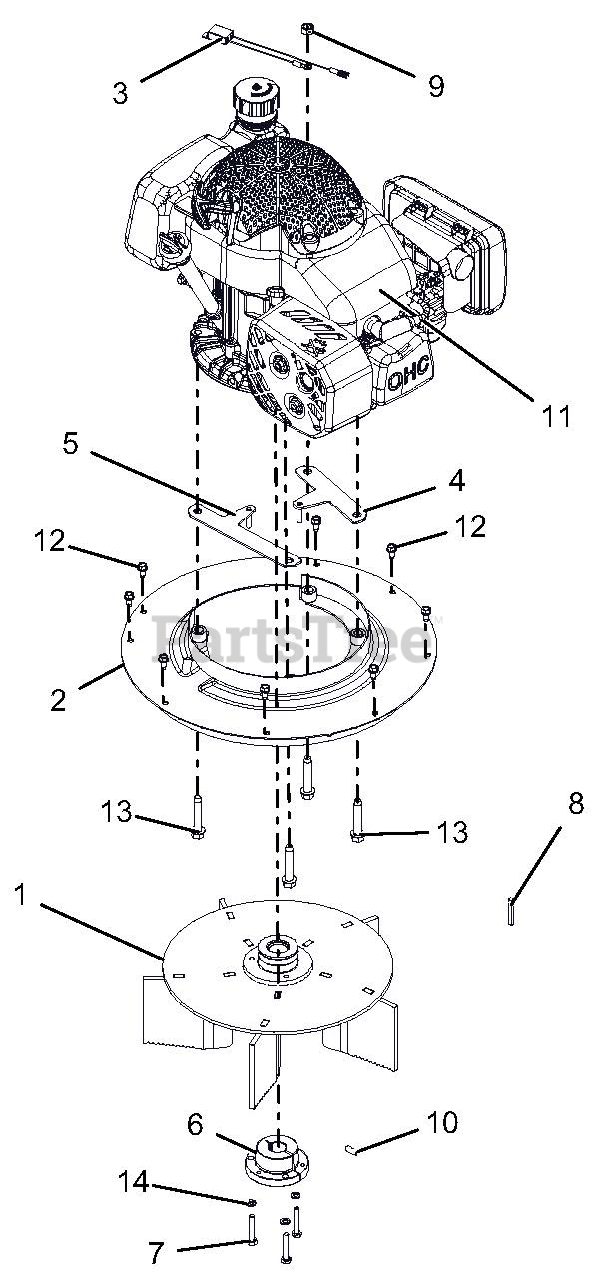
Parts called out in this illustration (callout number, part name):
1	WLDMT, IMPELLER - APV TAPER
2	WLDMT, ENGINE PLATE-RED
3	HARNESS, WIRE APV
4	WLDMT, BRKT - APV BELT FNGR S
5	WLDMT, BRKT - APV BELT FNGR R
6	BUSHING, TAPER -SPLIT 7/8" (SDS)
7	BLT-HEX .25-20X1.50 GR5 YWZC
8	KEY-SQ .188X.188X1.50 SAE 8630
9	NUT-LK-CTR .38-16 YWZC
10	SCR-SET, 25-20X.75 SKHCUPDL REV
11	ENGINE, SUBARU - EA190 (CE)
12	SCR-TAP .25-20X.50 HWH TR YWZ
13	SCR-TAP .38-16X2.00 HWH TR YZ
14	WSHR-LK .25X.062 REG YWZC
